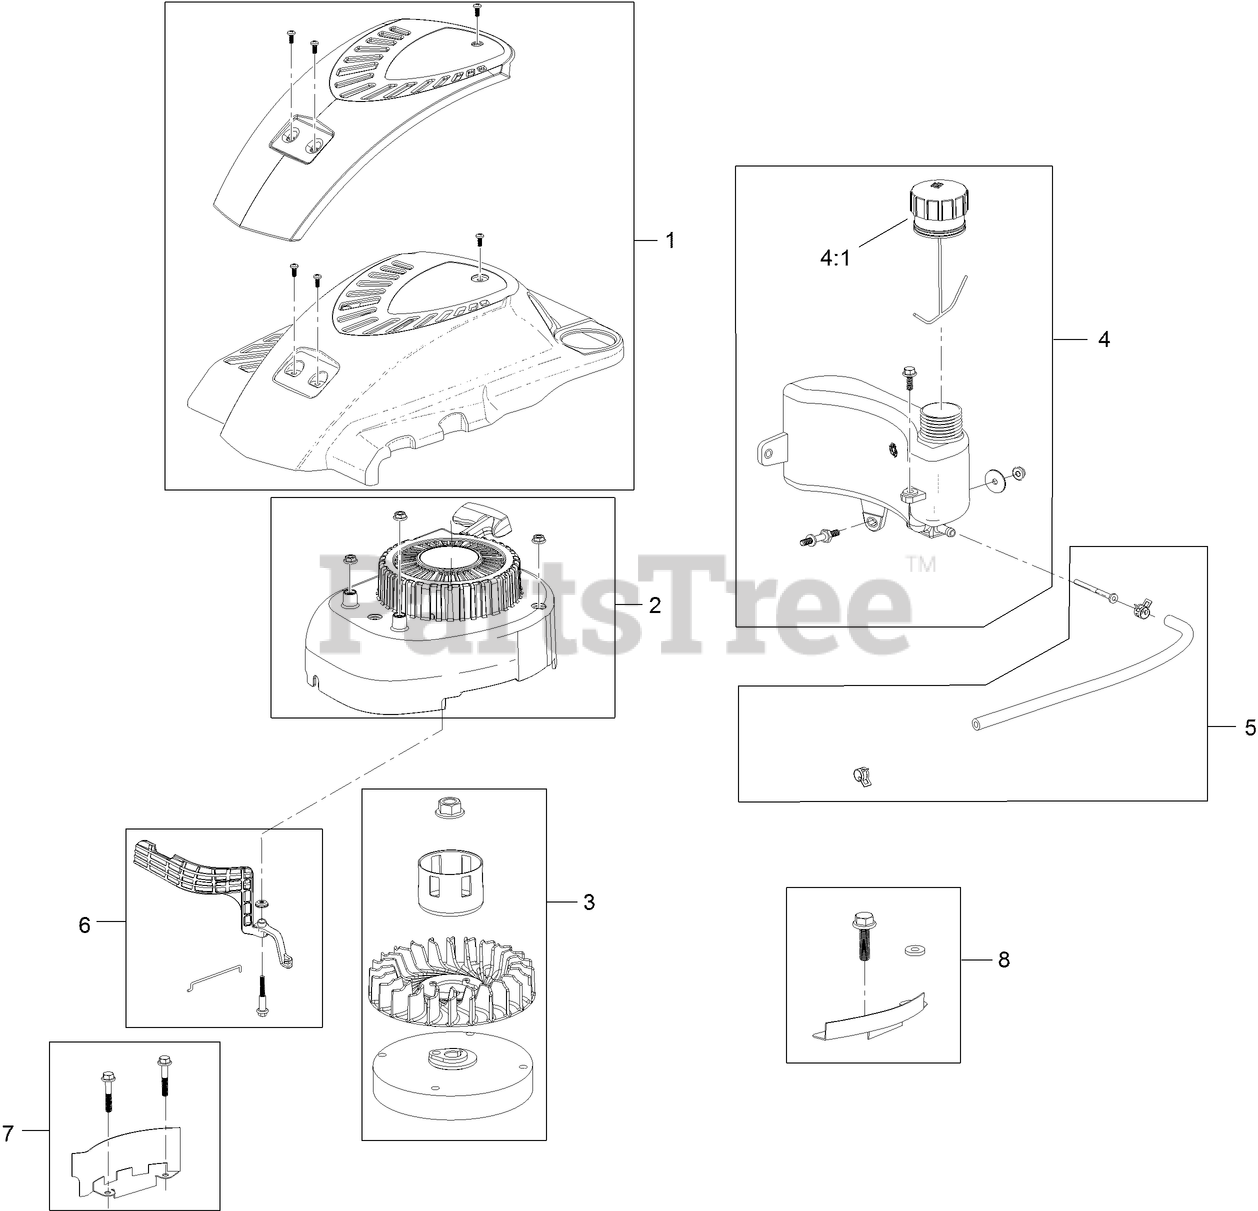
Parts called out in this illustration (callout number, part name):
1	SHROUD ASM
2	RECOIL AND BLOWER SHROUD KIT
3	FLYWHEEL AND FAN KIT
4	FUEL TANK KIT
4:1	CAP-FUEL
5	FUEL LINE KIT
6	AIR VANE KIT
7	FLYWHEEL SHIELD KIT
8	FLYWHEEL GUARD KIT
